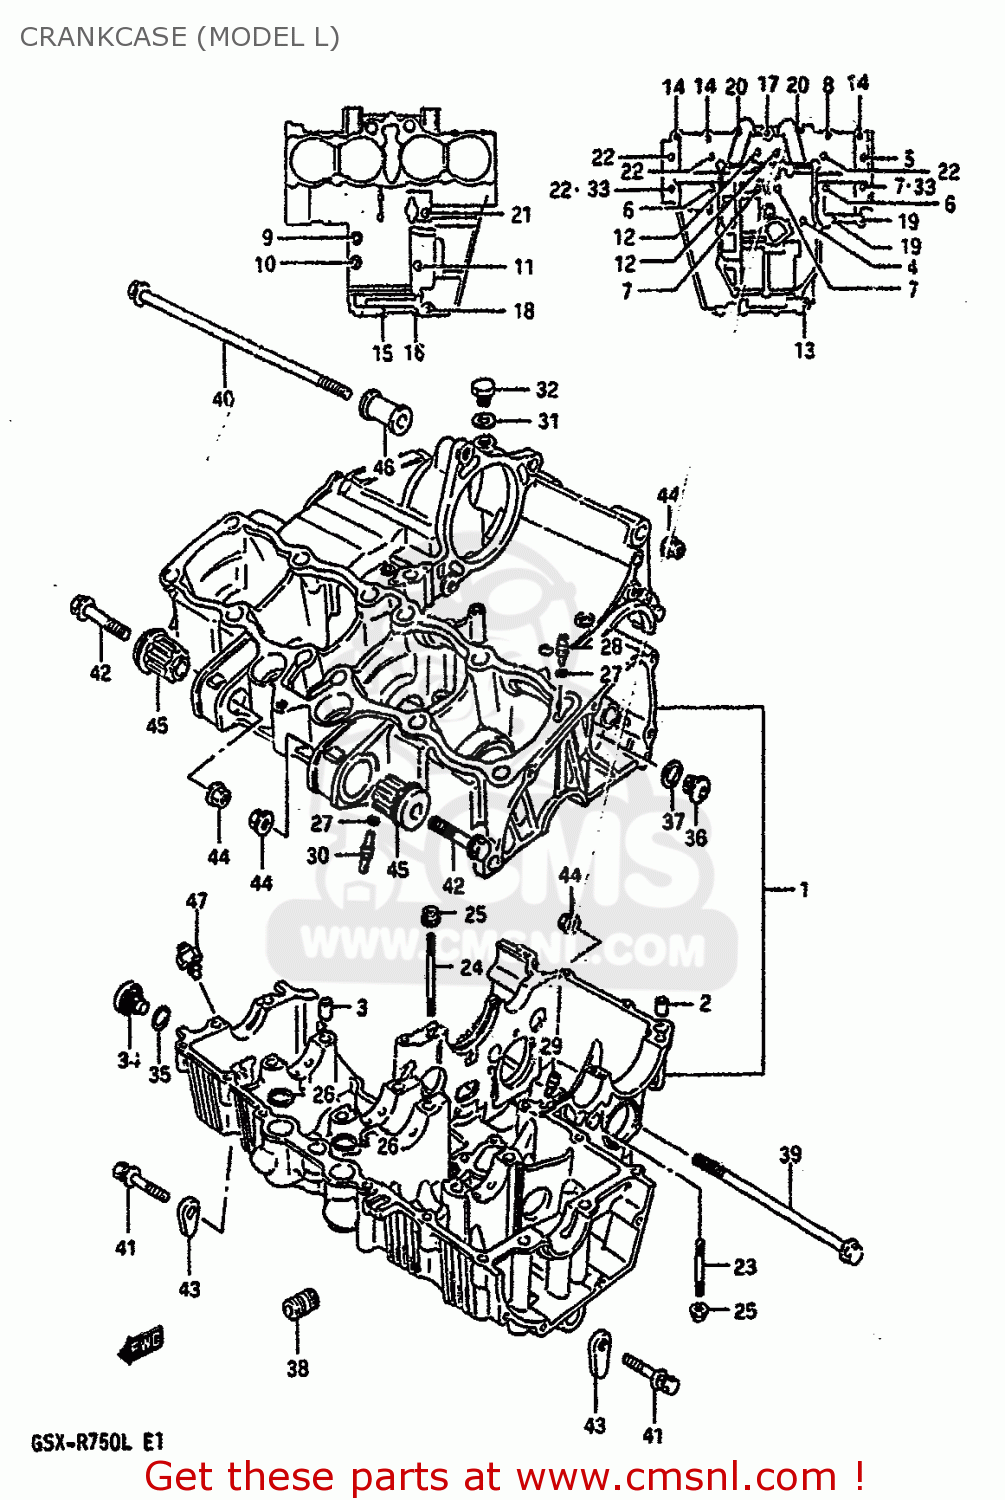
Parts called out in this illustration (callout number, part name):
1	CRANKCASE SET
2	PIN(10.4X13X22)
3	PIN (11X20)(SUS)
4	BOLT(6X105)
5	BOLT
6	BOLT(8X125)
7	BOLT 8X115
8	BOLT 6X35
9	BOLT
10	BOLT
11	BOLT
12	BOLT
13	BOLT 8X60
14	BOLT 6X35
15	BOLT
16	BOLT
17	BOLT 6X50
18	BOLT ,6X60
19	BOLT
20	BOLT
21	BOLT
22	BOLT
23	STUD BOLT
24	STUD BOLT
25	NUT
26	O RING(D:2.5,ID:21)
27	O RING(D:1.2,ID:4)
28	JET,AIR
29	JET
30	JET,OIL GALLERY
31	GASKET(12.1X16.2X3.7) (NAS)
32	PLUG(12X9)
33	GASKET(8.5X17X2.3) (NAS)
34	PLUG
35	O RING(D:2.4,ID:16.8)
36	PLUG
37	GASKET(14X19.2X2) (NAS)
38	UNION,OIL STAND
39	BOLT 10X150
40	BOLT(10X175)
41	BOLT
42	BOLT 10X55
43	NUT
44	NUT
45	BUSH,ENGINE MOUNTING
46	SPACER,ENGINE MOUNT
47	SWITCH ASSEMBLY
48	WASHER
49	BUSH,ENGINE MOUNTING
50	SPACER,ENGINE MOUNT
51	SWITCH ASSEMBLY
